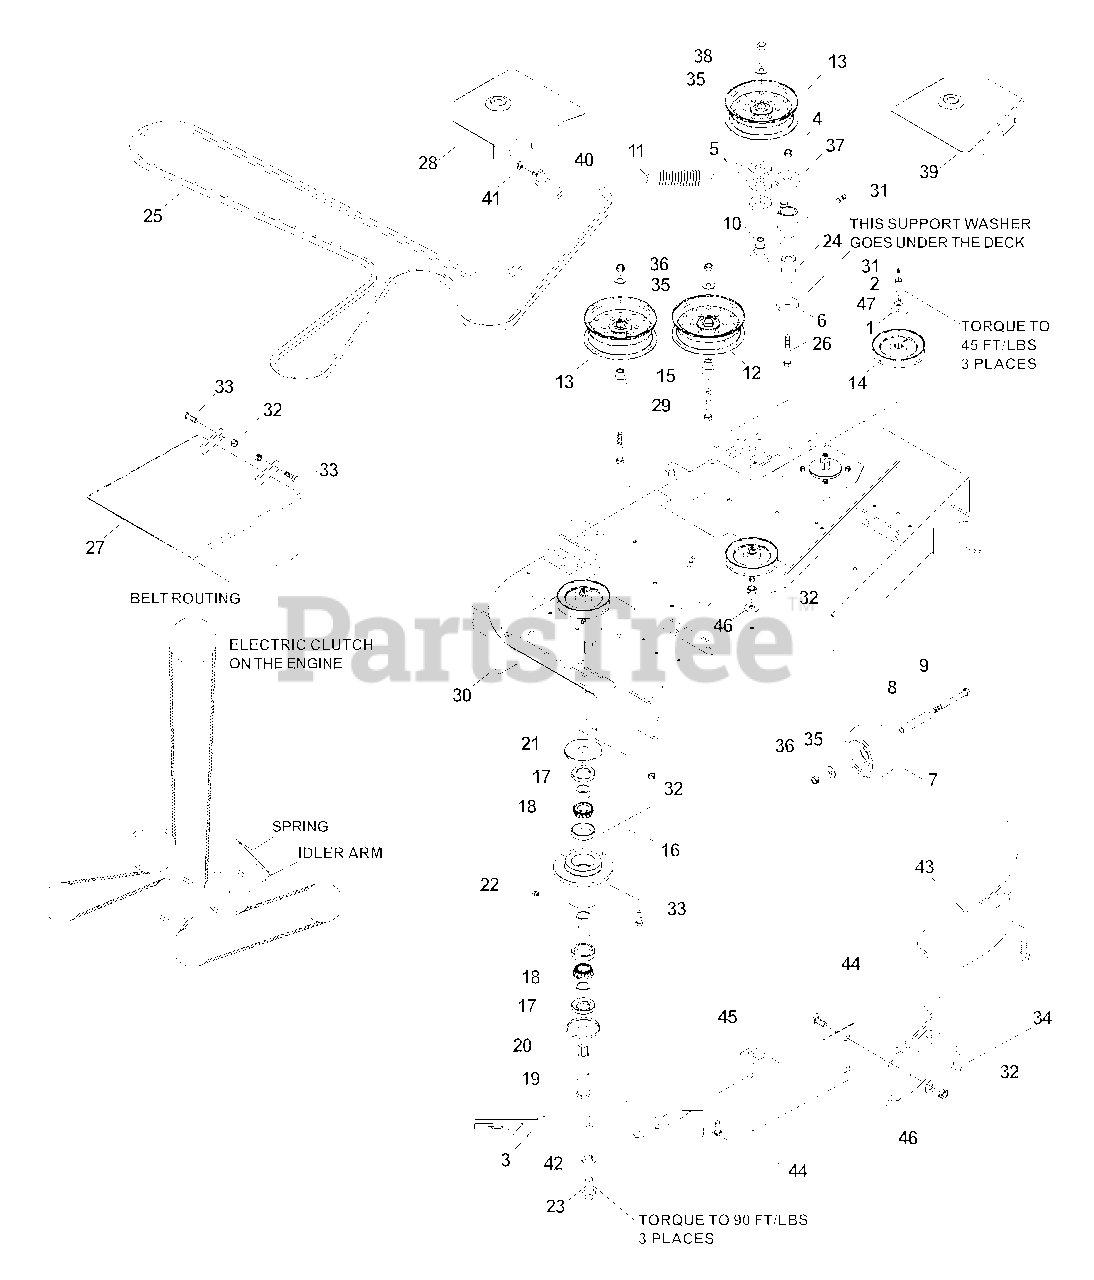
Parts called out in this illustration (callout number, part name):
1	HEAVY WASHER
2	HCS 7/16-20 X 1 1/2, SPECIAL
4	NUT, 1/2-13, NYLOC
5	BUSHING, MACHINE
6	SUPPORT WASHER
7	ANTI-SCALP ROLLER
9	HCS, 3/8-16 X 3 1/2
12	IDLER PULLEY
13	IDLER PULLEY (TALL)
14	PULLEY
15	IDLER BUSHING
16	SPINDLE, COMPLETE
17	SHAFT SEAL
19	SPINDLE
20	DUST CAP, BOTTOM
21	DUST CAP, TOP
22	GREASE POPET
23	HCS, 5/8-18 X 1 1/4
24	PIVOT BUSHING
26	HCS, 1/2-13 X 3 1/4
27	DEFLECTOR CHUTE
28	SHIELD, RIGHT
29	HCS, 3/8-16 X 2 1/2
30	DECK W/DECALS
31	ZERK
32	NUT, 5/16-18, CENTER LOCK
33	HCS, 5/16-18 X 1
34	HCS, 5/16-18 X 3/4
35	WASHER 3/8 FLAT
36	NUT, 3/8-16 CENTER LOCK
37	WASHER, 1/2
38	HCS, 3/8-16 X 1, SERR. HD.
39	SHIELD, LEFT
40	KNOB
42	LOCKWASHER, 5/8
43	BAFFLE, MAIN
44	RHSNB, 5/16-18 X 5/8
45	BAFFLE, CENTER
46	WASHER, 5/16
47	LOCKWASHER, 7/16
